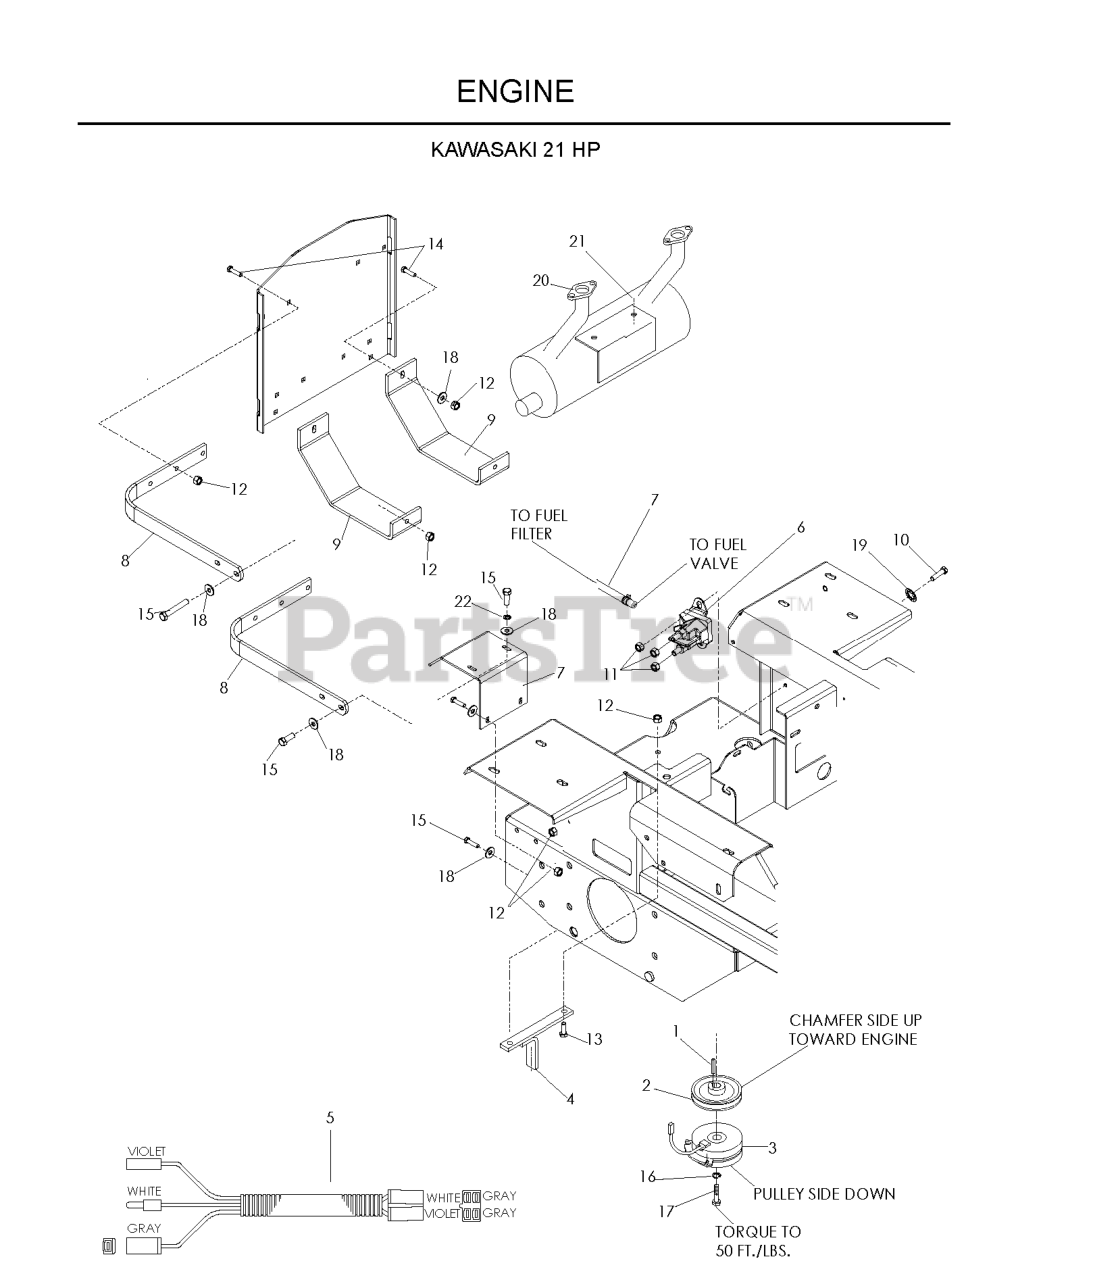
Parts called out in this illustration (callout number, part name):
1	KEY, 1/4 SQ X 1 1/4
3	CLUTCH-200 FT LB(RPLS 5218-102
4	CLUTCH TIE DOWN
5	KAW PIGTAIL
7	MUFFLER BRACKET BLACK
8	ENGINE SHROUD BRKT
9	SKID PLATE
10	HCS 1/4C X 5/8
11	NUT.1/4-20.HEX.NYLOC.ZD
12	NUT 5/16 NYLOC
13	HCS 5/16C X 1 3/4
14	RHSSNB 5/16C X 1.0
15	HCS 5/16C X 1
16	WASHER 7/16 LOCK
17	BOLT 7/16F X 2 1/2
18	WASHER 5/16 FLAT
19	WASHER 1/4 INT TOOTH
20	EXHAUST GASKET - KAW
21	MUFFLER KAWASAKI GEN II
22	WASHER.LOCK.HVY.HLCL.SPR.5/16
